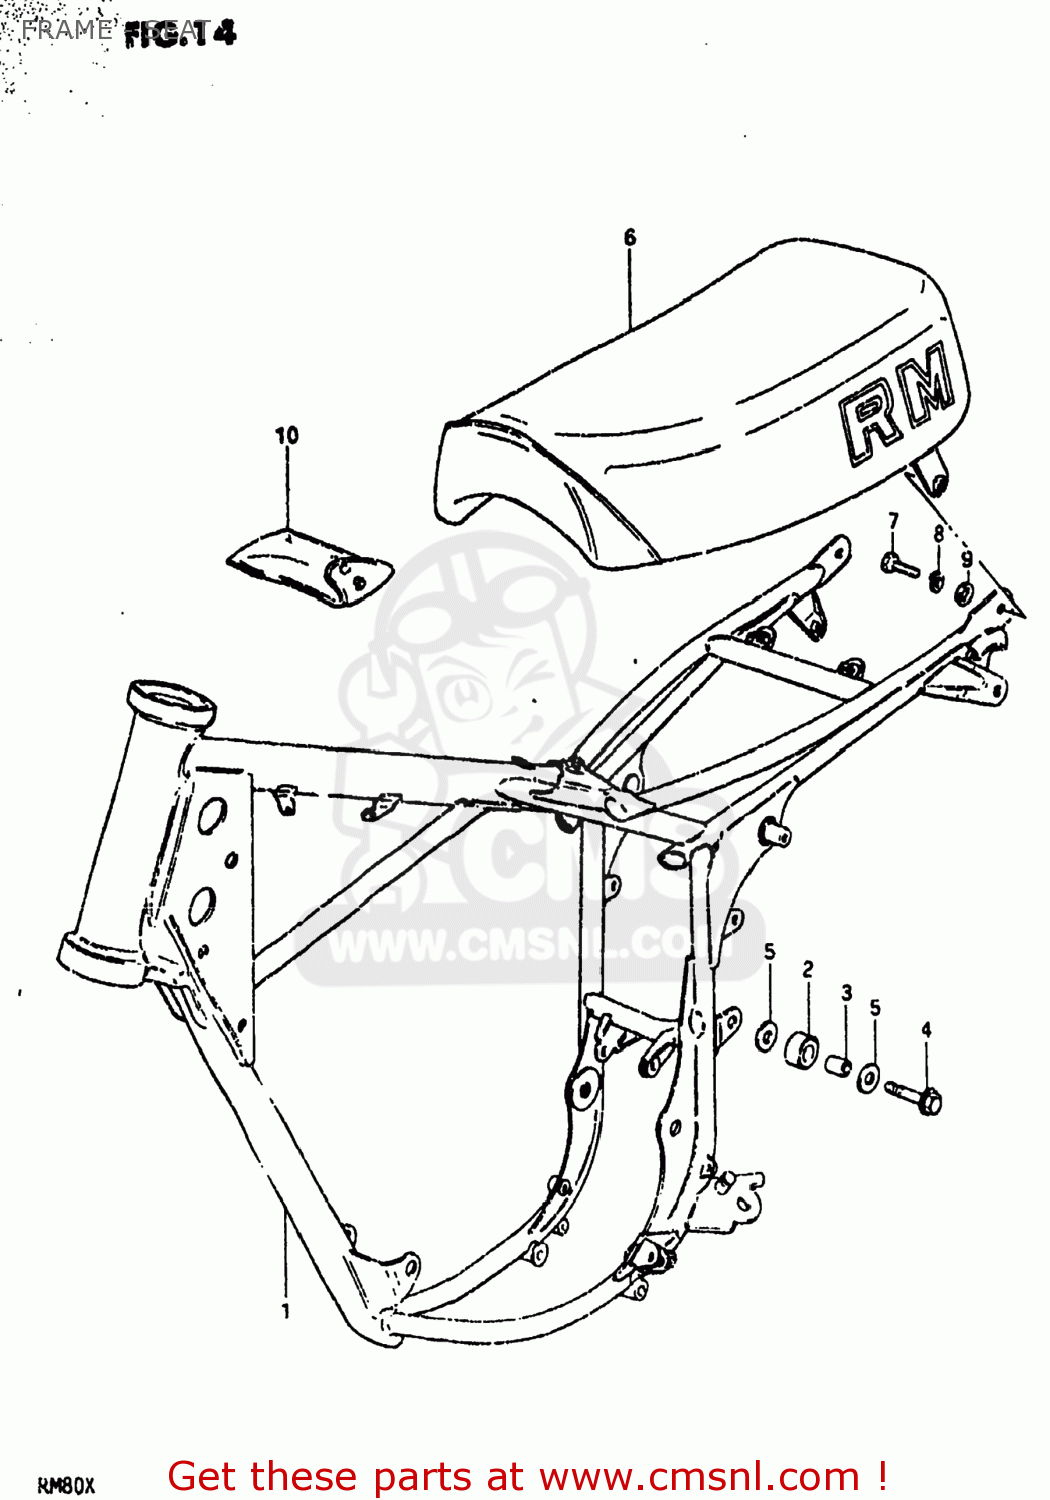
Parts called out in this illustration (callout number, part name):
1	FRAME
2	ROLLER,CHAIN CONTROL
3	SPACER,CHAIN CONTROL
4	BOLT(8X45)
5	WASHER
6	SEAT ASSEMBLY
7	BOLT
8	LOCK WASHER
9	WASHER
10	TOOL SET
